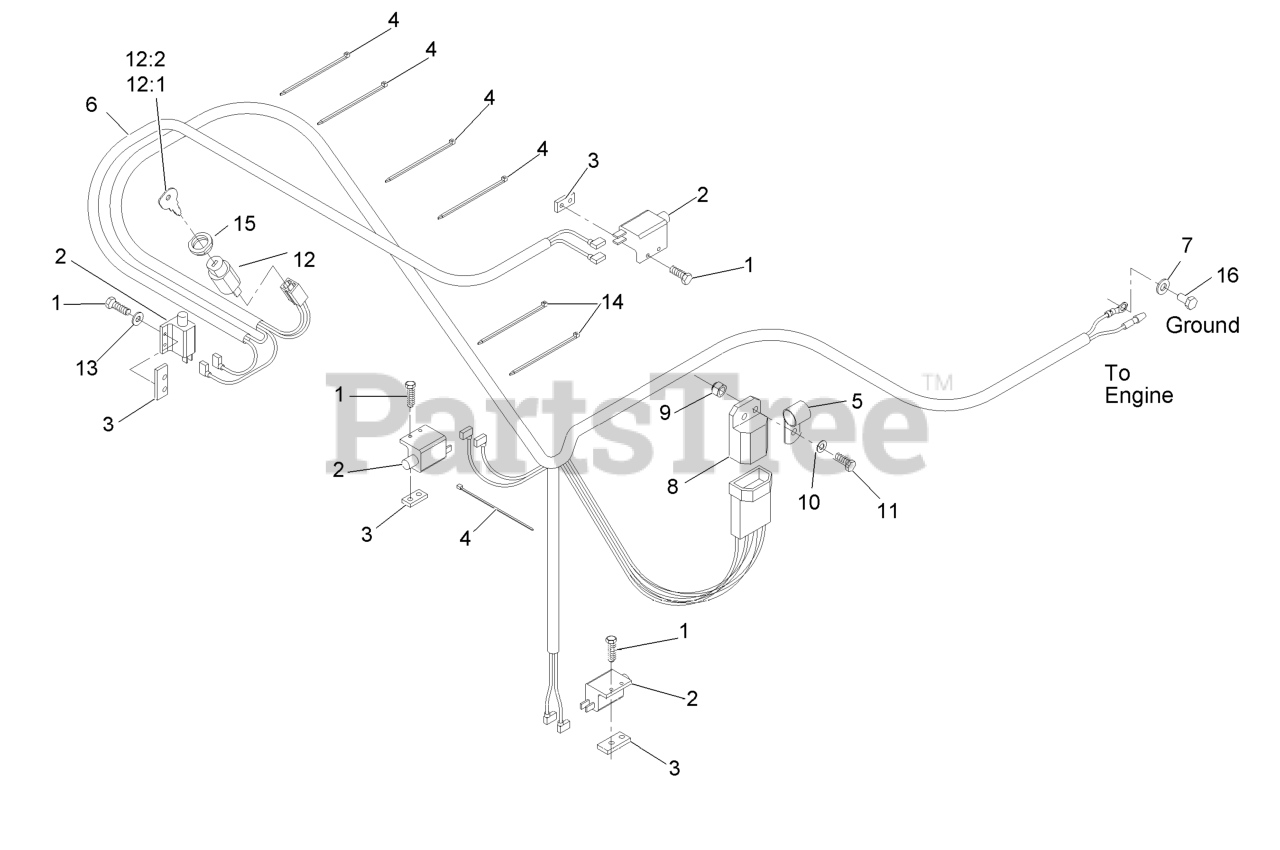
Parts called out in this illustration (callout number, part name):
1	SCREW-PPH
2	SWITCH-OPEN, NORMALLY
3	PLATE-TAPPED
4	TIE-CABLE
5	CLIP-LOOM
6	HARNESS,WIRING KA PULL ST
7	WASHER-PLAIN
8	MODULE-INTERLOCK
9	NUT-LOCK, NI
10	WASHER-FLAT
11	SCREW-HH
12	SWITCH & KEY (INCLUDES NU
12:1	KEYS-IGNITION (SPARE PAIR
12:2	KEY-IGNITION
13	WASHER-FLAT
14	TIE-PLASTIC
15	NUT-SWITCH, IGNITION
16	SCREW-HH
